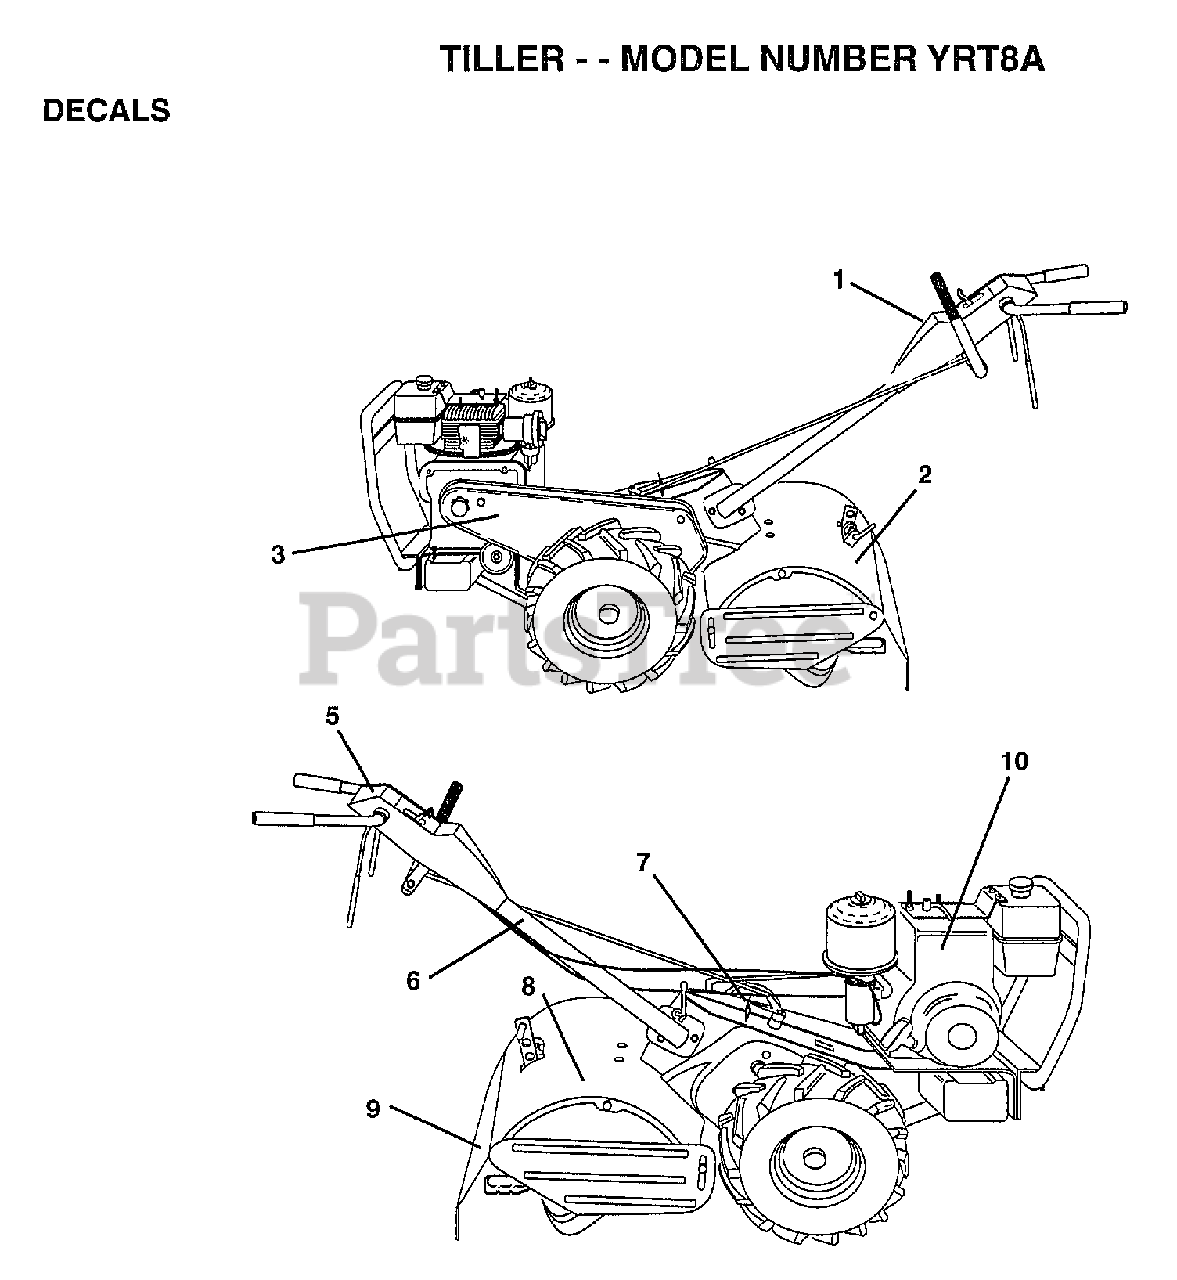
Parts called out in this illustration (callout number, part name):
1	DECAL.PNL.CONTROL
2	DECAL SHIELD TINE
3	DECAL LOGO GUARD
5	DECAL INST PNL 21
6	DECAL TI
7	DECAL INDICT SHIF
8	DECAL TI
10	DECAL, BRIGGS & STRATTON
